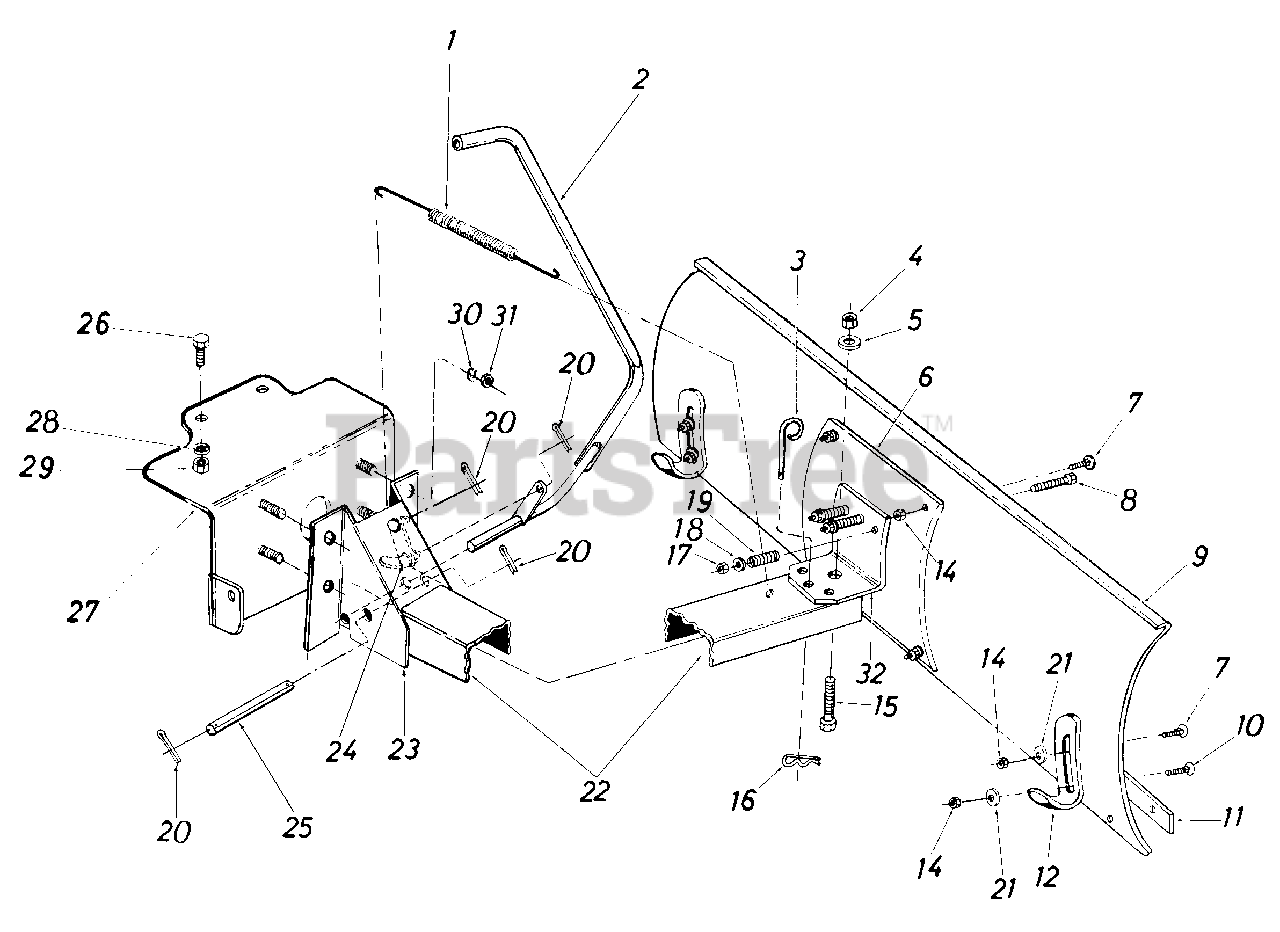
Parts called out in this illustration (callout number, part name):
1	Extension Spring
2	Lift Handle Ass'y.
3	Pivot Lock Pin
4	Hex Cent. L.-Nut 1/2-13 Thd.
5	Fl.-Wash. 17/32 I.D. x 1.25" Lg.
6	Reinforcement Plate
7	Carriage Bolt 5/16-18 x .75" Lg.
8	Hex Scr. 3/8-16 x 3.75" Lg. Grade 5
9	42" Blade
10	Carriage Bolt 5/16-18 x 1.00" Lg.
11	42" Wear Plate
12	Shoe Skid
14	HexCent. L.-Nut 5/16-18 Thd.
15	Hex Scr. 1/2'-13 x 1.25" Lg.
16	Hair Pin Cotter
17	Hex Cent. L.-Nut 3/8-16 Thd.
18	Fl.-Wash. 3/8" I.D.
19	Compression Spring
20	Cotter Pin 1/8" Dia. x 1.00" Lg.
21	Fl.-Wash. 5/16" I.D.
22	Push Bar Channel
23	Pivot Support Bracket
24	Lift Link
25	Channel Pivot Shaft
26	Hex Scr. 3/8-16 x 1.00" Lg. Grade 5
27	Support Bracket Ass'y.
28	L.-Wash. 3/8 I.D.
29	Hex Nut 3/8-16 Thd.
30	L.-Wash. 3/8" I.D.
31	Hex Jam Nut 3/8-16 Thd.
32	Support Bracket
